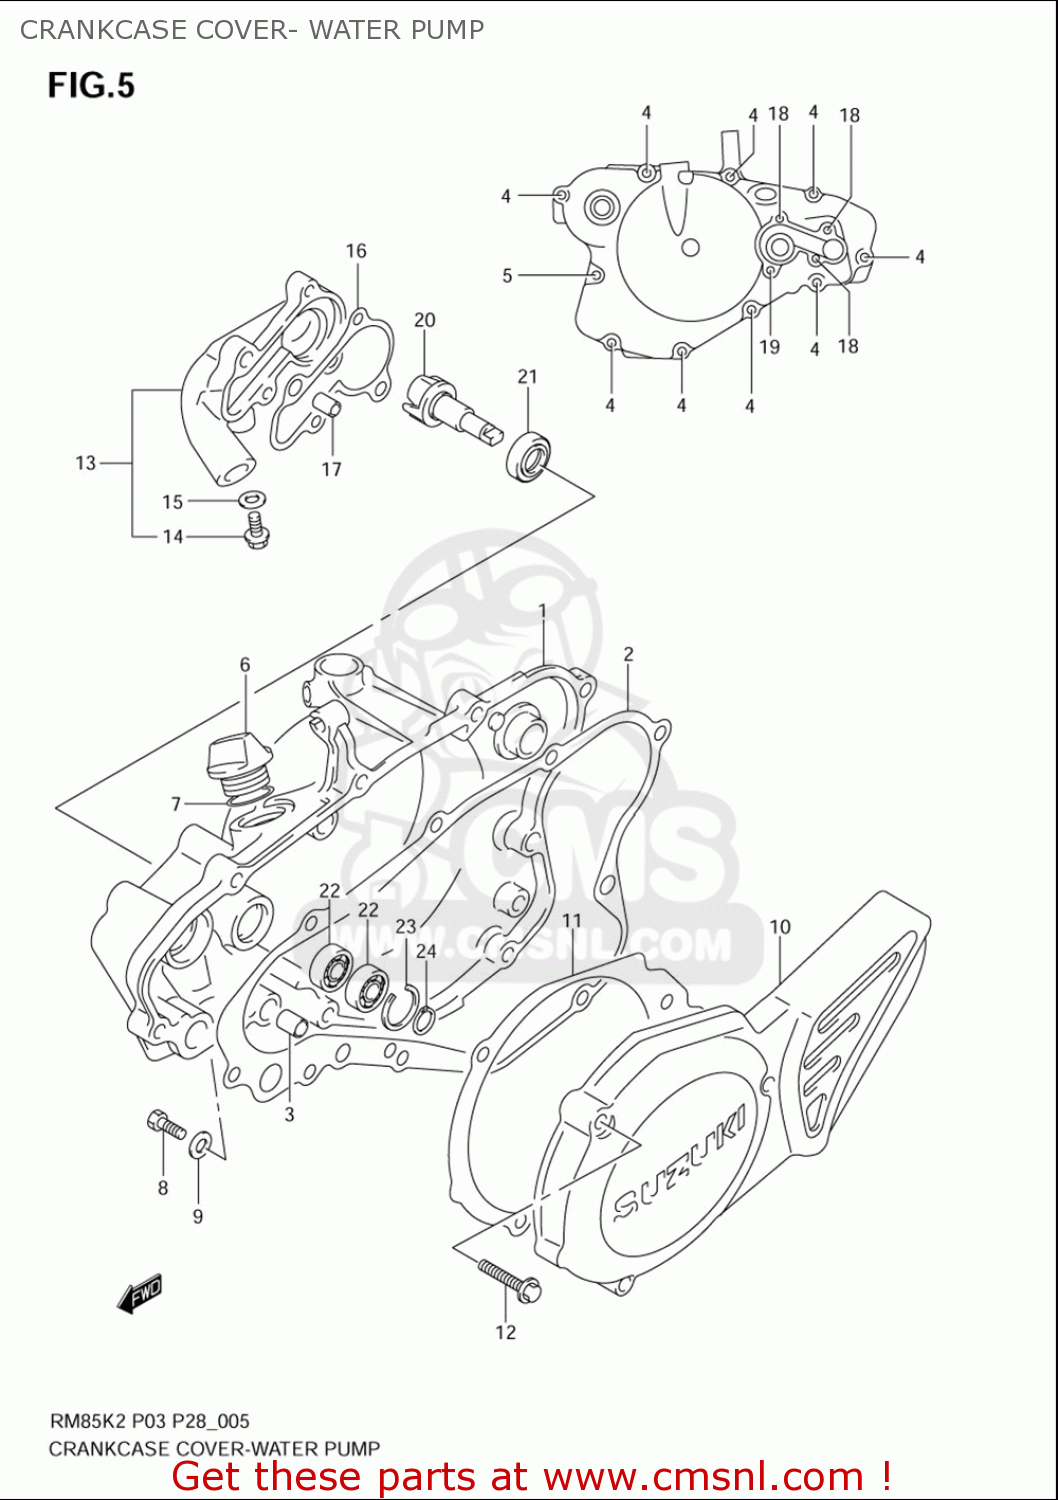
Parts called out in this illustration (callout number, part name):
1	COVER,CLUTCH
2	GASKET,CLUTCH COVER (NAS)
3	PIN
4	BOLT(6X25)
5	BOLT(6X35)
6	PLUG,OIL FILLER
7	O RING(D:3.1,ID:16.8)
8	BOLT
9	GASKET(6.2X11X1).2 (NAS)
10	COVER,MAGNETO
11	GASKET,MAGNETO COVER (NAS)
12	SCREW
13	CASE ASSY,WATER PUMP
14	BOLT
15	WASHER
16	GASKET,WATER PUMP CASE (NAS)
17	PIN
18	BOLT,6X20
19	BOLT(6X30)
20	IMPELLER,WATER PUMP
21	SEAL,WATER PUMP OIL
22	BEARING
23	CIRCLIP
24	CIRCLIP
